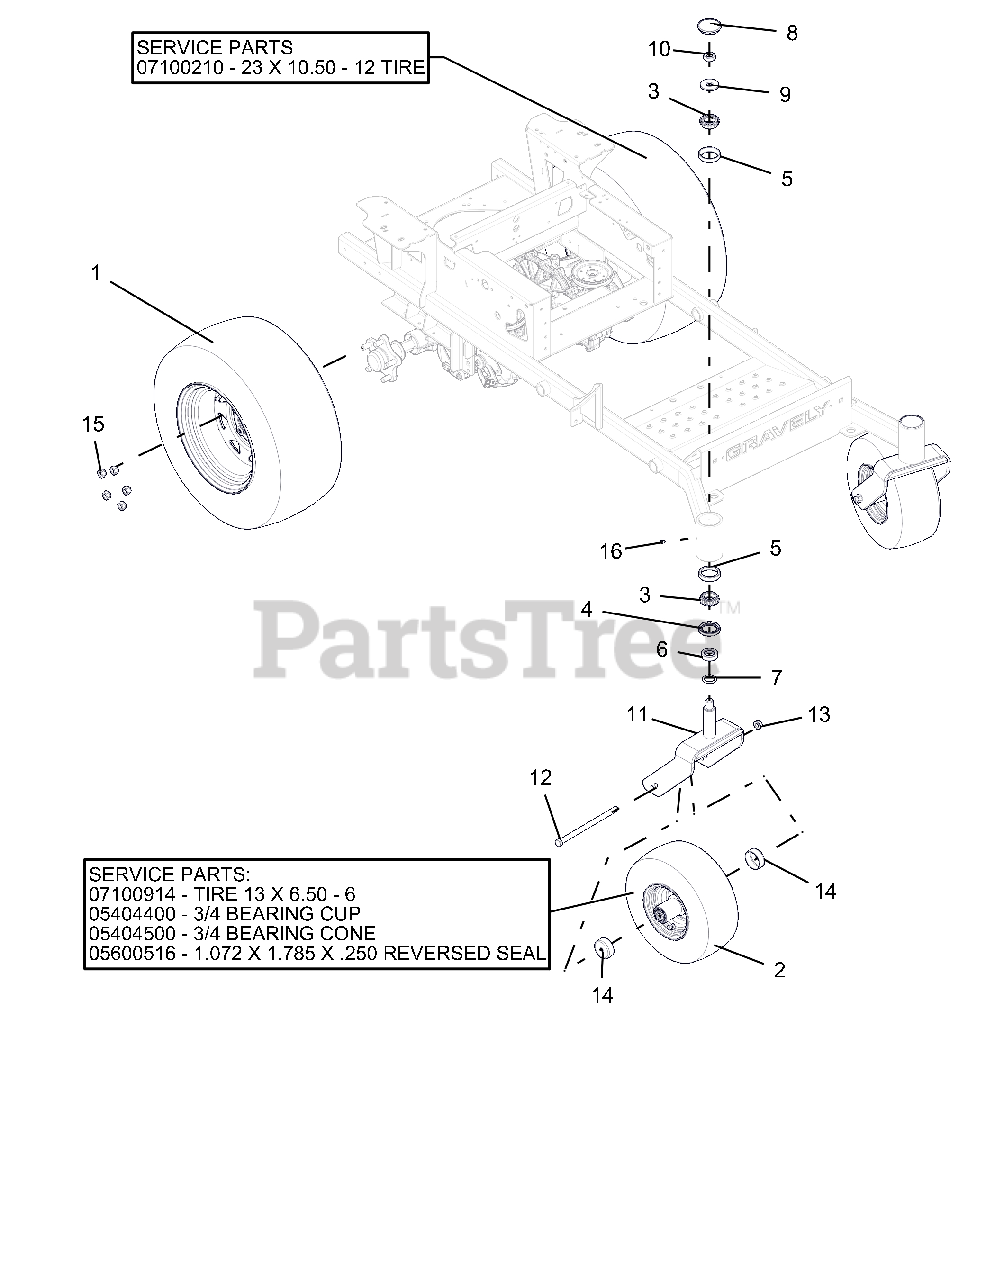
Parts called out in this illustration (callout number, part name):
1	TIRE/WHEEL, ASM 23 x 10.5-12
1	23 X 10.50-12 TIRE
2	TIRE/WHEEL, 13 X 6.50-6 SMOOTH
2	TIRE 13 X 6.50-6
2	3/4 BEARING CUP
2	3/4 BEARING CONE
2	1.072 X 1.785 X .250 REVERSED SEAL
3	BRG, CONE 1.250 X .660
4	SEAL, OIL 1.75 X 2.332 X .312
5	BRG, CUP 2.328 X .465
6	SPCR, FRONT CASTER FORK
7	O-RING, .139 W X 1.234 ID
8	CAP, DUST
9	WSHR-FL-STL.812X2.00X.148YWZC
10	@NUT-LK-TOP-JAM .75-16 YWZC
11	WMT, CASTER FORK - RED
12	BLT-HEX .50-13X9.00 GR5 YWZC
13	NUT, LK-TOP-FLG .50-13 YWZC
14	SHIELD, WHEEL BEARING
15	NUT, LUG .500-13
16	FITTING, .250-28 FLUSH MOUNT GREASE
